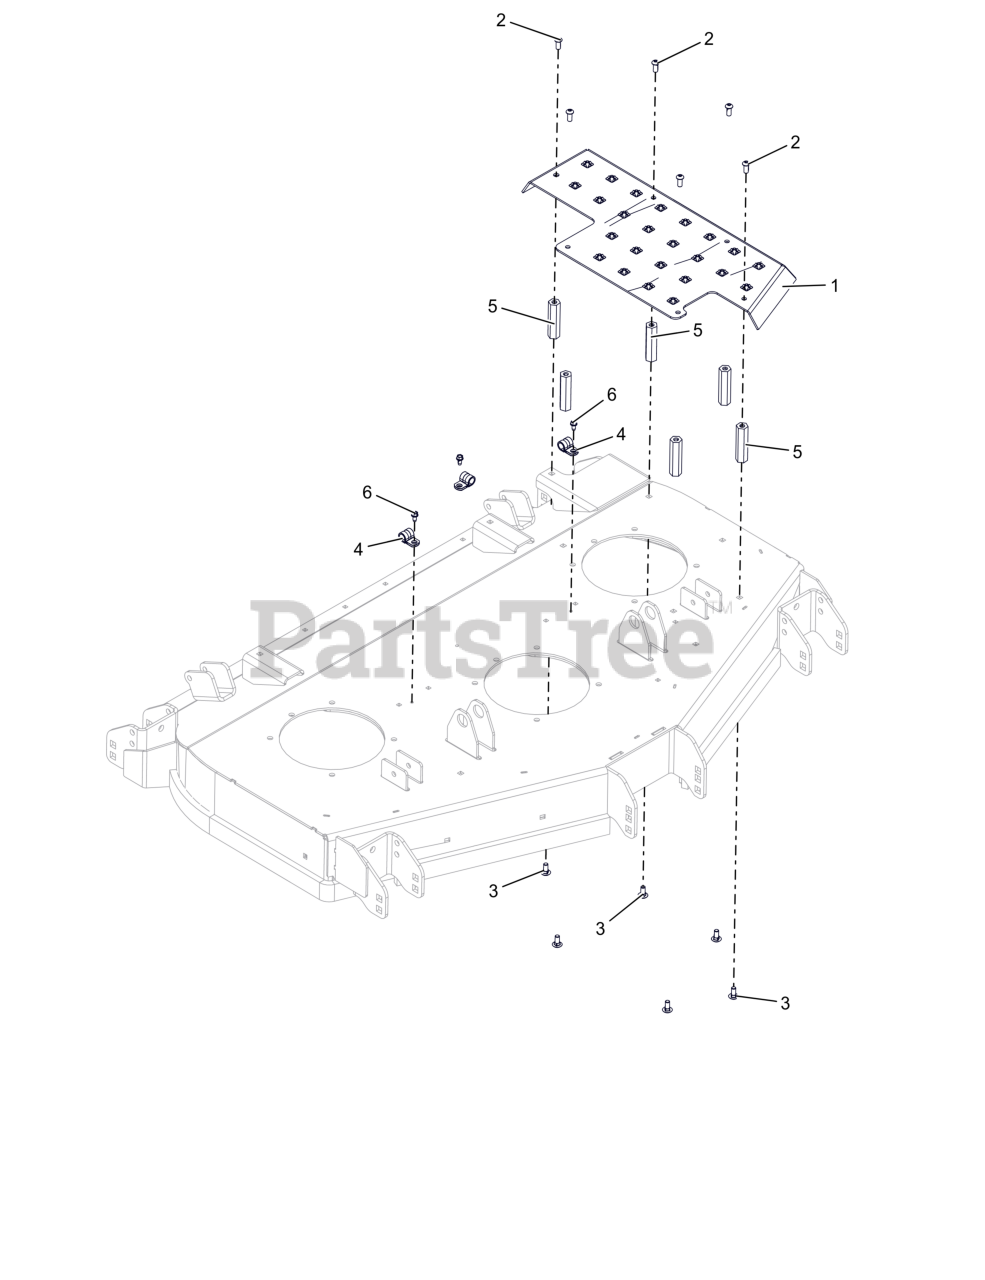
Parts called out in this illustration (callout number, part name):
1	PLATFORM, WLDMT 48 RD DECK STEP (RED)
2	SCR-SKH .31-18X.75 BTNHD YWZC
3	BTL,RHSN .313-18 X 0.75 G5 ZCC LT
4	CLAMP, CUSHIONED STEEL
5	NUT, COUPLING .31-18 X 3.00
6	SCR-TAP .25-20X.50 HWH ZCC
